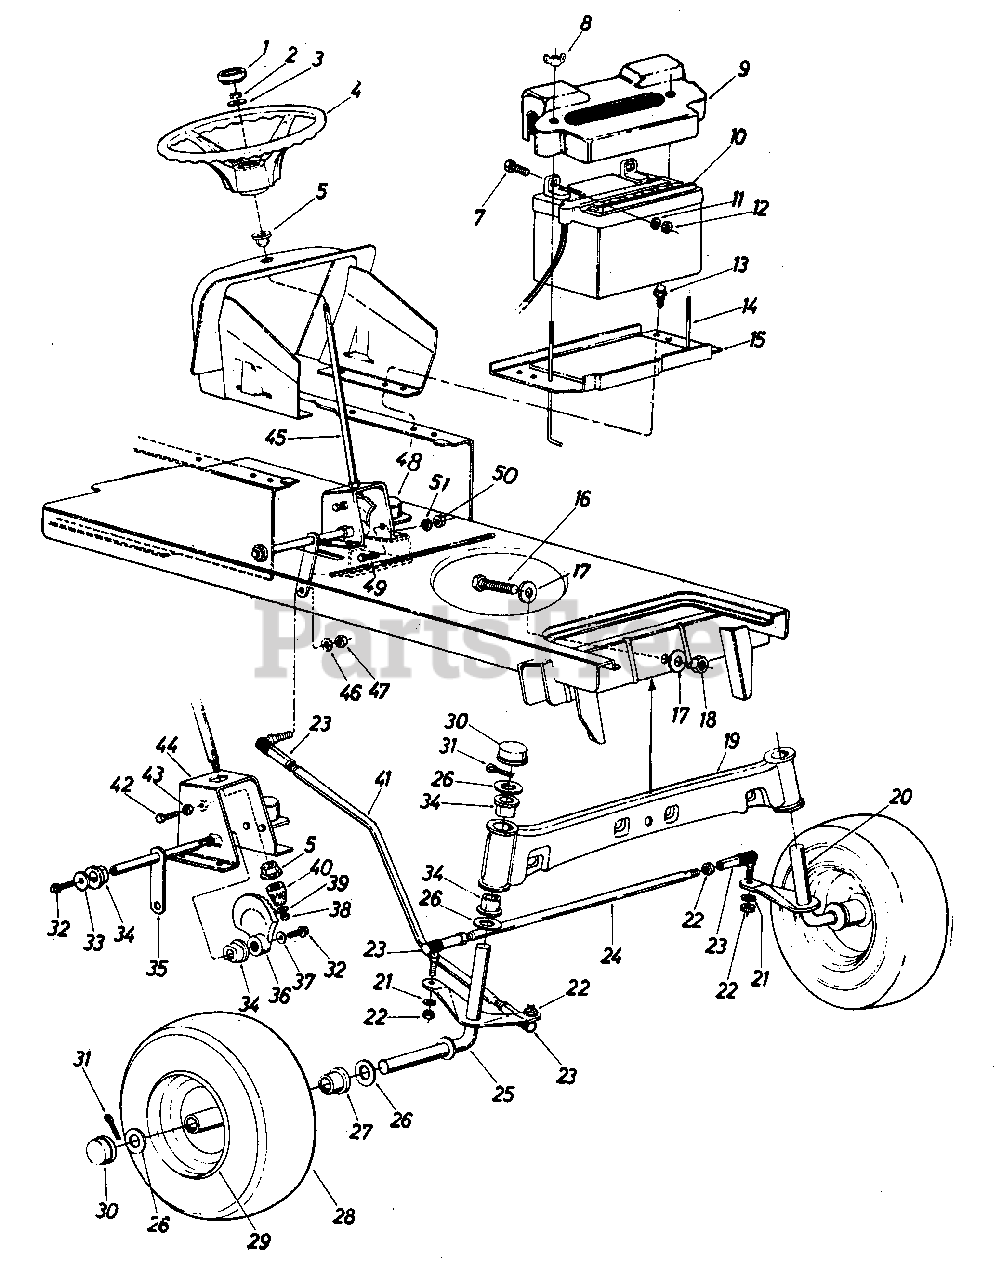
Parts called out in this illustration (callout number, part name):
1	Steering Wheel Cap
2	Hex Cent. L-Nut 5/16-18 Thd .
3	Bell-Wash. 5/16" I.D. x .87" O.D. x .060
4	Steering Wheel
5	Plastic Hex Bearing 5/8" I.D.
7	Hex Scr. 1/4-20 x .62" Lg.
8	Wing Nut Plastic 1/4-20 Thd.
9	Battery Cover
10	12-V Battery
11	L-Wash. 1/4" Scr*
12	Hex Nut 1/4-20 Thd.*
13	Hex Thd. Rolling Scr. 1/4-20 x.50" Lg.
14	Battery Hold Down Rod
15	Battery Plate
16	Hex Scr. 5/8-18 x 2.50" Lg.*
17	Flat Wash. .66" I.D. x 2.25" O.D. x .17
18	Hex Cent. L-Nut 5/8-18 Thd.
19	Front Pivot Bar Assly.
20	Front Axle Ass'y. L.H.
21	L-Wash. 3/8" Scr.*
22	Hex Jam Nut 3/8-24 Thd.
23	Ball Joint Assy.
25	Front Axle Ass'y. R.H.
26	Fl-Wash. .780 I.D. x 1.59 O.D.
27	Flange Bearing
28	Front Wheel Ass'y. Comp.
29	Front Wheel Rim Only
30	Dust Cover
31	Cotter Pin 5/32" Dia. x 1.00" Lg.*
32	Hex Scr. 3/8-24 x .75" Lg. Grade 5
33	Fl-Wash. 3/8 I.D. x 1.25 O.D. x .090
34	Flange Double "D" Brg. .753 I.D.
35	Steering Arm Shaft Ass'y.
36	Side Gear Steering
37	Bell-Wash. 3/8" I.D.
38	Hex Cent. L-Nut 5/16-24 Thd .
39	Fl-Wash. 5/16" I.D. x .62 O.D. x .059
40	Pinion Gear Steering
42	Hex Nylon Scr. 3/8-16 x 1.25" Lg.
43	Hex Nut 3/8-16 Thd.*
44	Steering Gear Sup. Ass'y.
45	Steering Shaft
46	L-Wash. 3/8" Scr.*
47	Hex Nut 3/8-24 Thd.*
48	Solenoid
49	Hex Scr. 1/4-20 x .62" Lg.
50	Hex Nut 1/4-20 Thd.*
51	L-Wash. 1/4" Scr.*
